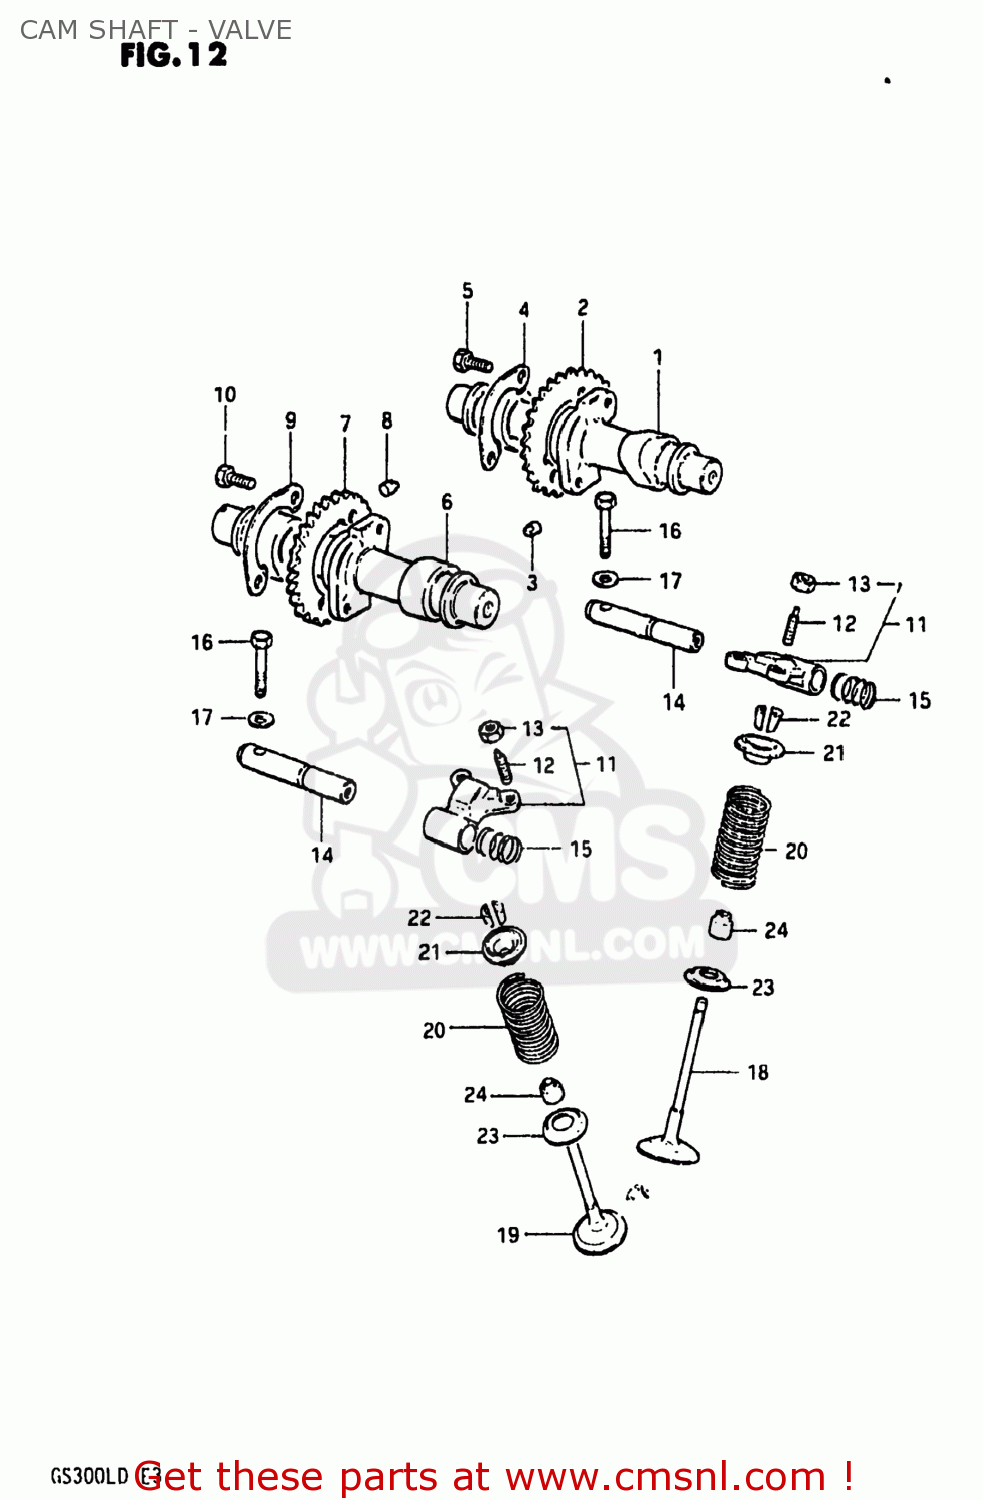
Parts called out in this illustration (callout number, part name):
1	CAMSHAFT
2	SPROCKET,INTAKE CAMSHAFT
3	PIN,SPROCKET
4	WASHER,CAM CHAIN SPROCKET
5	BOLT(6X12.5)
6	CAMSHAFT,EXHAUST
7	SPROCKET,EXHAUST CAMSHAFT
8	PIN,SPROCKET
9	WASHER,CAM CHAIN SPROCKET
10	BOLT(6X12.5)
11	ARM,VALVE ROCKER
12	SCREW,TAPPET ADJUSTING
13	NUT,ADJUSTING
14	SHAFT,VALVE ROCKER ARM
15	SPRING
16	BOLT
17	WASHER
18	VALVE,INTAKE
19	VALVE,EXHAUST
20	SPRING,VALVE
21	RETAINER,VALVE SPRING
22	COTTER VALVE
23	SEAT,VALVE SPRING
24	OIL SEAL
